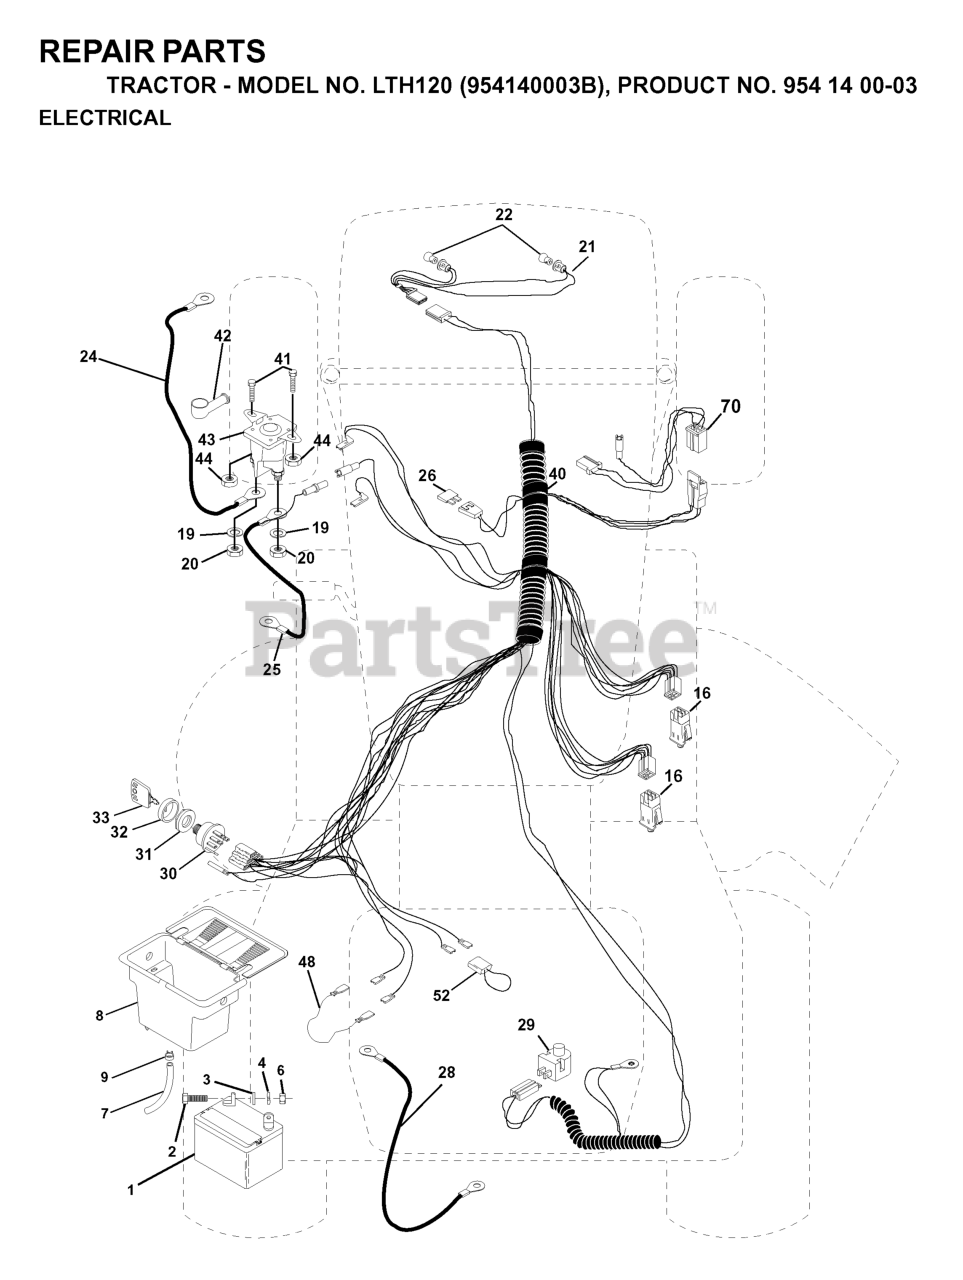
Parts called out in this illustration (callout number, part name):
1	BATTERY 12 VOLT 25 AMP
2	BOLT.HEX.1/4.X.3/4.DICHROMATE
4	LOCKWASHER
6	NUT
7	TUBE BATTERY DRAIN
8	CASE BATTERY MECH HINGE
9	HOSE CLAMP T
16	SWITCH INTERLOCK
19	LOCKWASHER
20	NUT
21	HARNESS LIGHT SOCKET
24	BATTERY CABLE GT
25	CABLE BATTERY
28	CABLE T
29	RP.SWITCH.PLUNGER.NC.GRAY
30	SWITCH.IGNITION.4.POSITION
31	NUT IGNITION
32	COVER SWITCH KEY
33	KEY.MOLDED.GENERIC
40	HARNESS IGN
41	BOLT
42	TERMINAL COVER
43	SOLINOID
44	Nut, Keps Blk Hex 1/4-20 UNC
48	ADAPTER.AMMETER
52	WIRE PROTECTION LOOP
70	HARNESS, ENGINE
